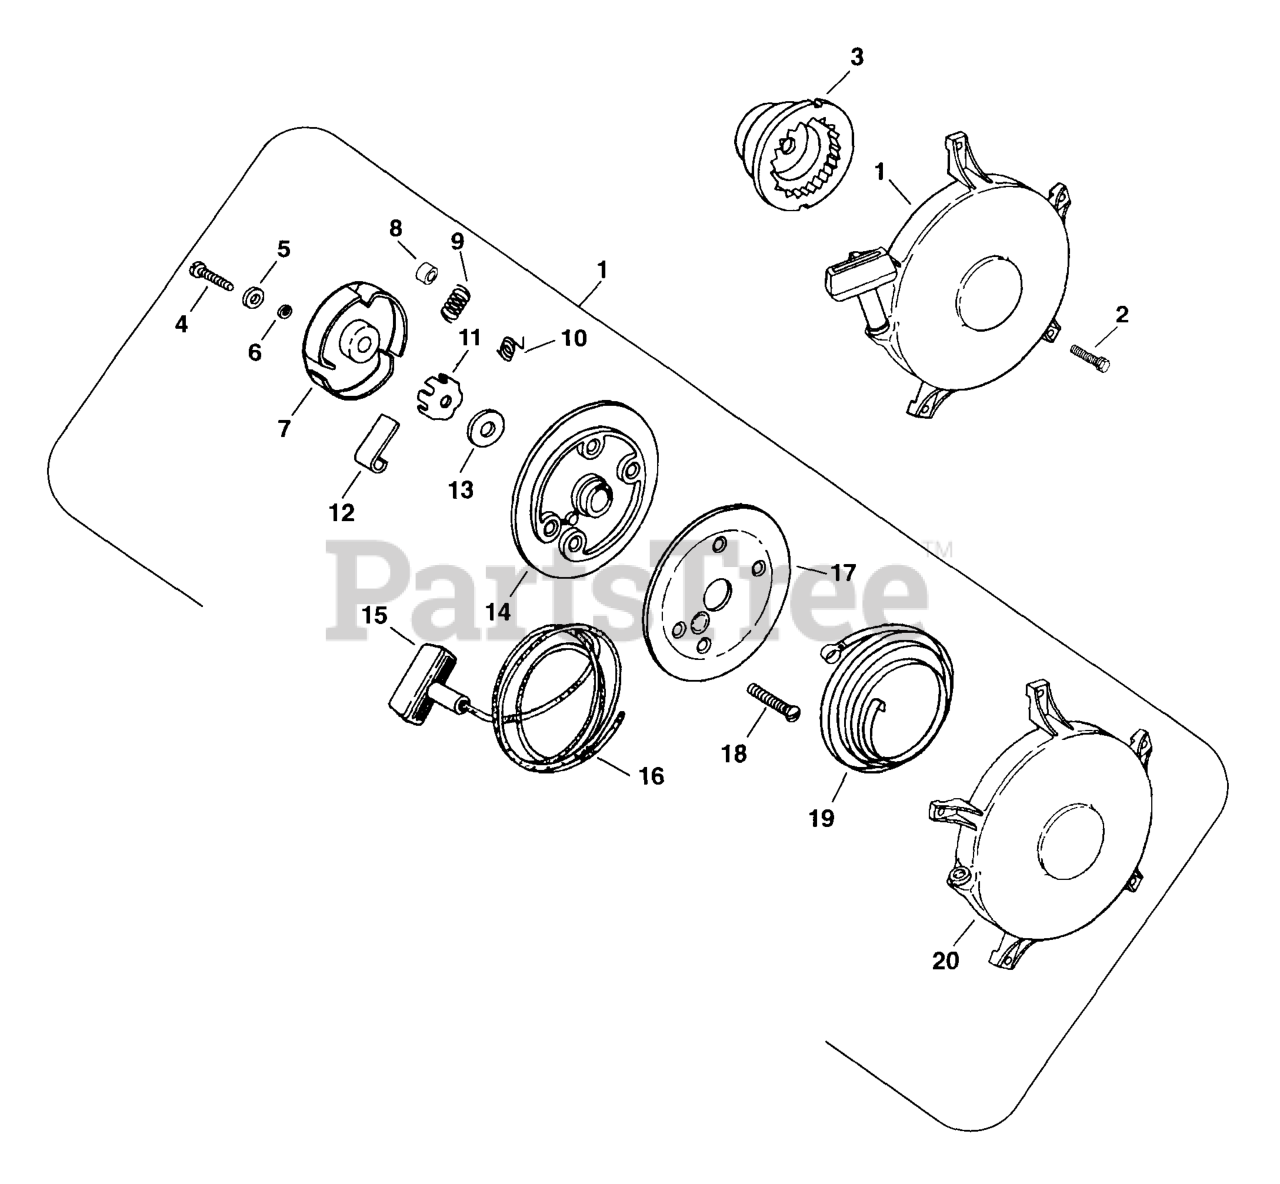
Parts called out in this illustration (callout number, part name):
1	STARTER
2	SCREW
3	CUP, DRIVE - DISCONTINUED
5	WASHER - DISCONTINUED
7	RETAINER
8	SPACER
9	SPRING - DISCONTINUED
12	DOGS - DISCONTINUED
15	HANDLE - USE 25 166 01
20	HOUSING - DISCONTINUED
